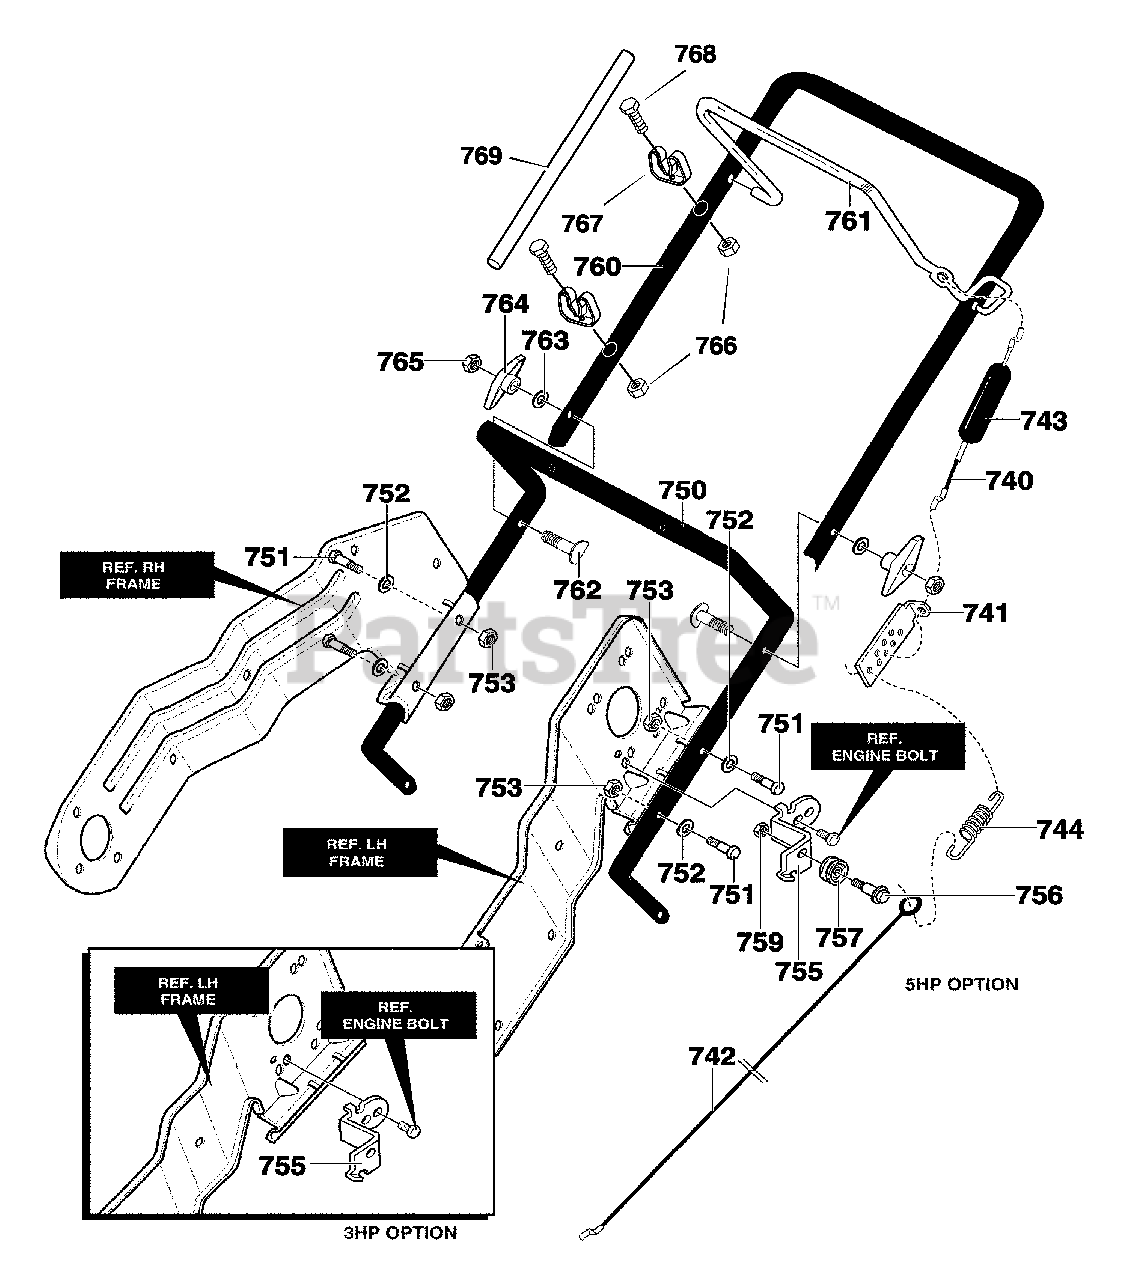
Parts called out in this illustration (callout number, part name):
740	CABLE, UPPER
741	BRACKET, CABLE ADJ
742	CABLE, LOWER CONTROL
743	BOOT, CLUTCH SPRING
744	SPRING, EXTENSION
750	HANDLE, LOWER
751	SCREW, 1/4-20X1.25
752	WASHER, FLAT
753	NUT, 1/4-20
755	BRACKET, CABLE
757	PULLEY
759	NUT, 1/4-20 YZ
760	UPPER HANDLE
761	BAIL, CONTROL
763	WASHER, FORM
764	KNOB, T 3.00 WD
765	NUT, 5/16-18
766	NUT 10-32
767	CLIP, RETAINER
768	SCREW 10-32
769	TOOL, CLEAN-OUT
